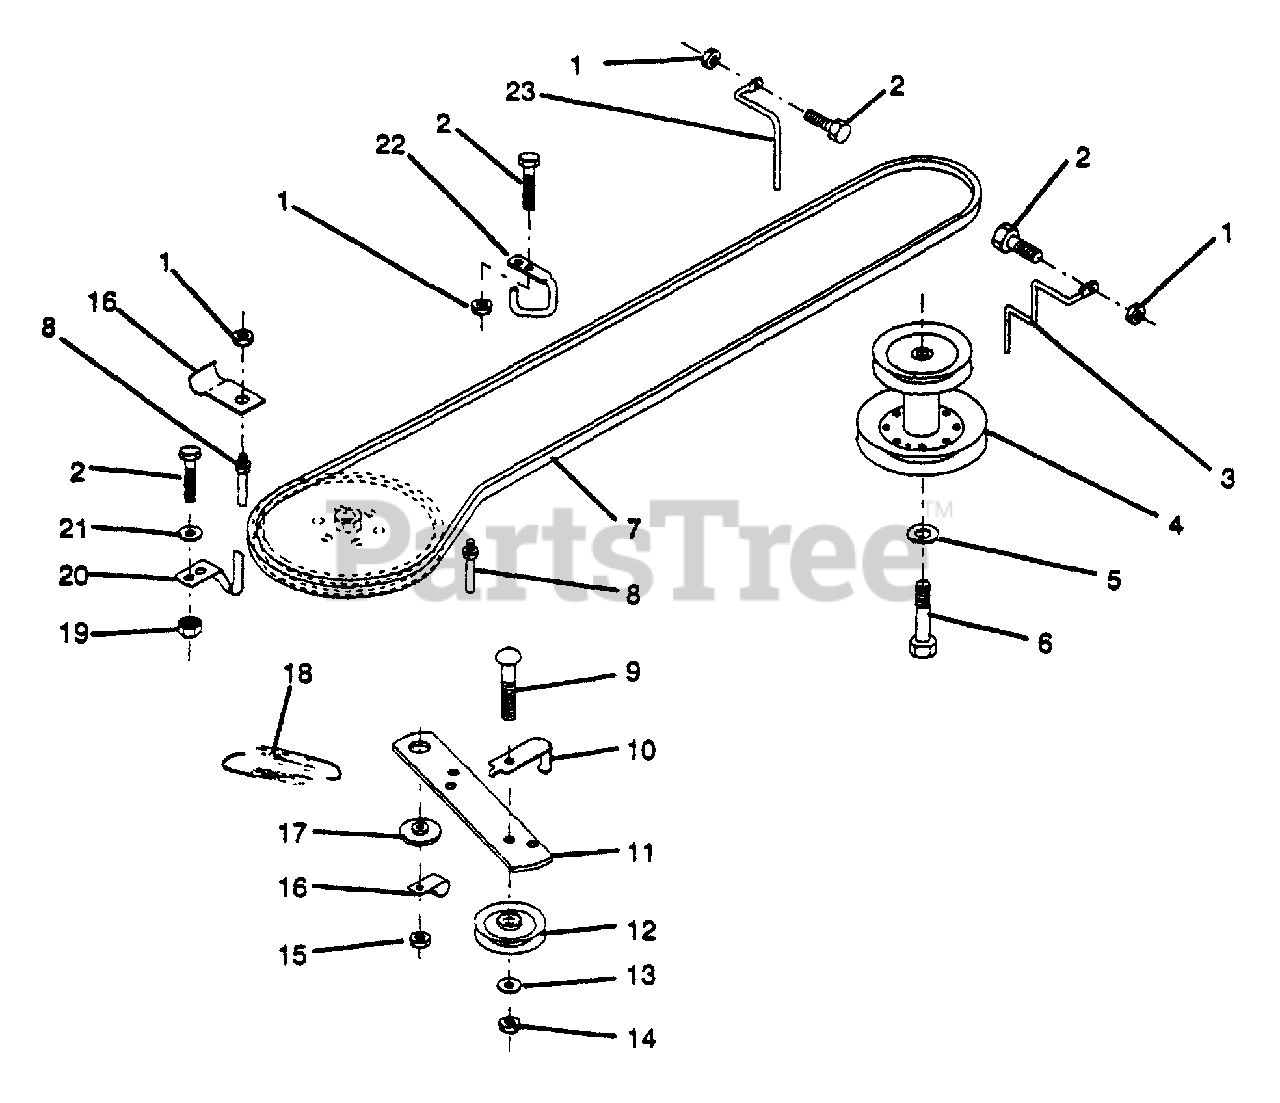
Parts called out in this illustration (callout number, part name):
1	Nut, Crownlock 5/16-18
2	Bolt, Hex Hd. 5/16-18 UNC x 3/4
3	Keeper, Engine Mower Drive R.H. Belt
4	Pulley, Engine
5	Washer, Lock Hvy. Helical Spring 7/16
6	Soft, Fin. Hex 7/16-20 UNF x 1-1/4 Gr. 8
7	Traction, V-Belt Drive
8	Keeper, T/A Ground Drive Belt
9	Bolt, Carriage 3/8-16 UNC x 1-1/2
10	Keeper, Belt Ground Drive Idler
11	Arm, Ground Drive Clutch
12	Idler, Flat
13	Washer 13/32 x 13/16 x 16 Ga.
14	Nut, Centerlock 3/8-16 UNC
15	Nut, Crownlock 3/8-16 UNC
16	Clip, Insulated
17	Spacer, Retainer
18	Spring, Extension
19	Nut, Keps 5/16-18 UNC
20	Keeper, T/A Ground Drive Belt
21	Washer 11/32 x 5/8 x 16 Ga.
22	Keeper, Frame Ground Drive Belt
23	Keeper, Engine Mower Drive L.H. Belt
